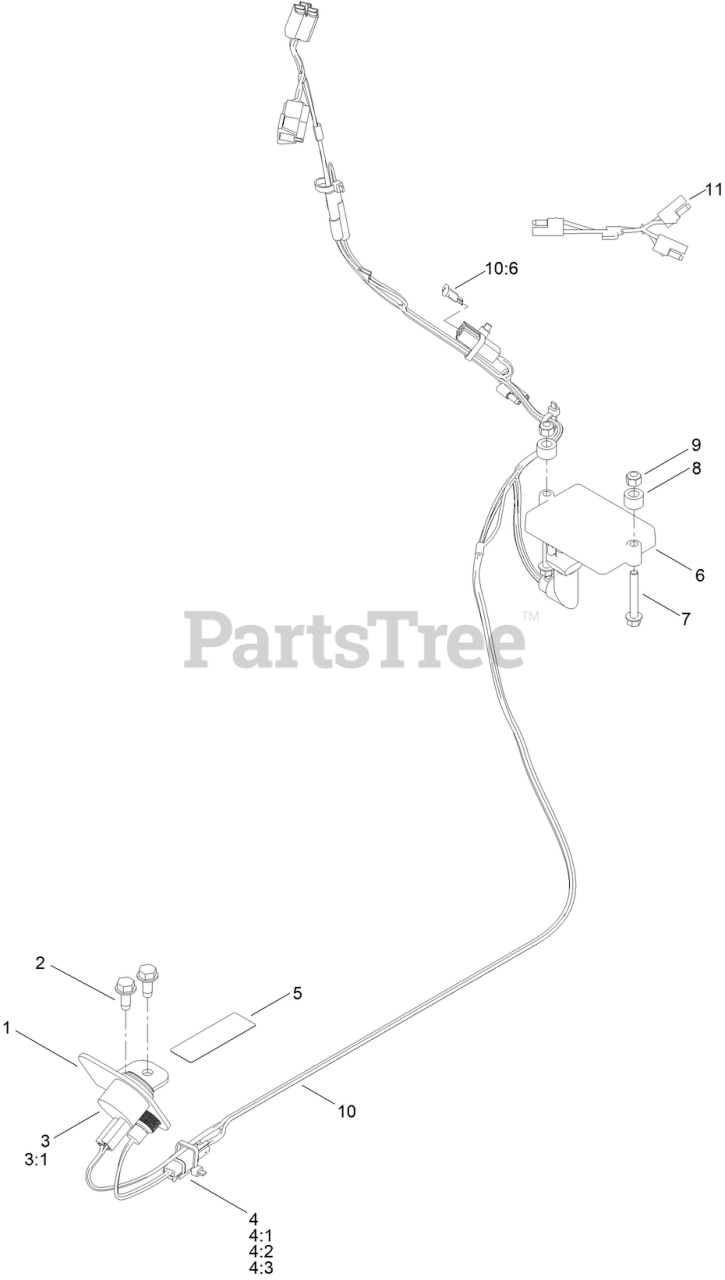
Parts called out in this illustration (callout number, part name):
1	BRACKET-LIGHT
2	SCREW-HWHTF
3	AUDIO ALARM ASM
3:1	NUT-PLASTIC, KNURLED
4	RED LED INDICATOR LAMP ASM
4:1	GASKET-LED
4:2	WASHER-LOCKING
4:3	NUT-FIXING
5	DECAL-SLOPE SENSOR
6	CONTROLLER (FASM-TSM-0802)
7	SCREW-HHF
8	SPACER
9	NUT-HEX
10	HARNESS-WIRE, SLOPE SNSR
10:6	FUSE-2 AMP
11	HARNESS,ACCESSORY ADD-ON
